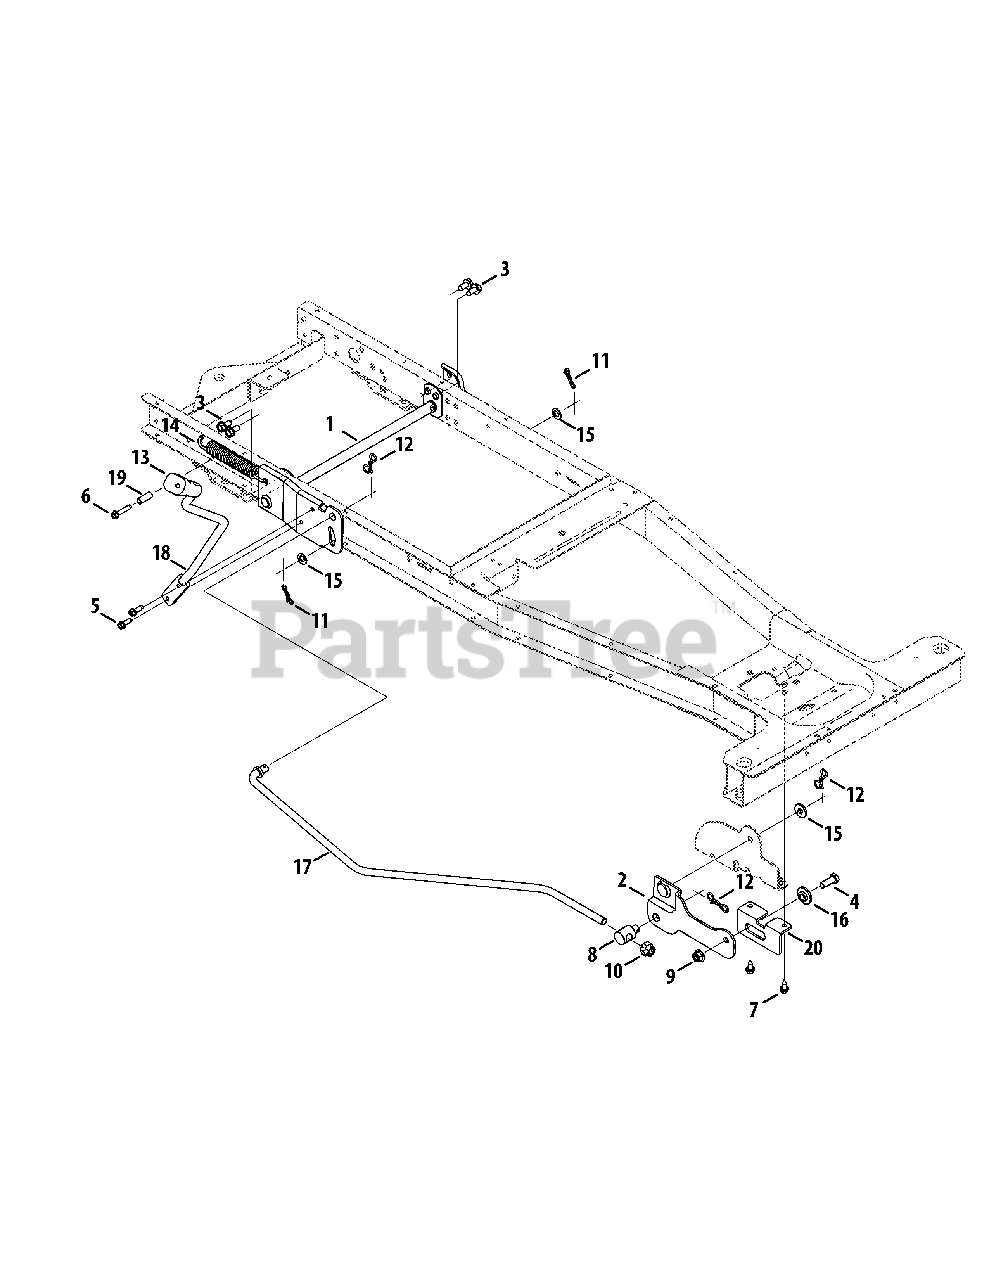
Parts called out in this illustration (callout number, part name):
1	Lift Assembly Shaft
2	Front Hanger Bracket Assembly
3	Tap Screw, 5/16-18, .750
4	Hex Head Screw, 3/8-16, 1.00
5	Tap Screw, 1/4-20, 0.750
6	Tap Screw, 1/4-20, 1.250
7	Tap Screw, 1/4-20 X .625
8	Ferrule, .50 X .50
9	Flange Lock Nut, 3/8-16
10	Flex Lock Nut, 1/2-13
11	Bow-Tie Cotter Pin, 72
12	Bow-Tie Cotter Pin, 91
13	Grip Handle, 1/2
14	Extension Spring, .85 OD X 5.915 LG
15	Flat Washer, .406 X .875 X .059
16	Shoulder Spacer, .625 ID X .169
17	Lift Link Rod
18	Deck Lift Rod
19	Spacer, .260 x .375 x 1.030 LG
20	Front Deck Mounting Bracket
